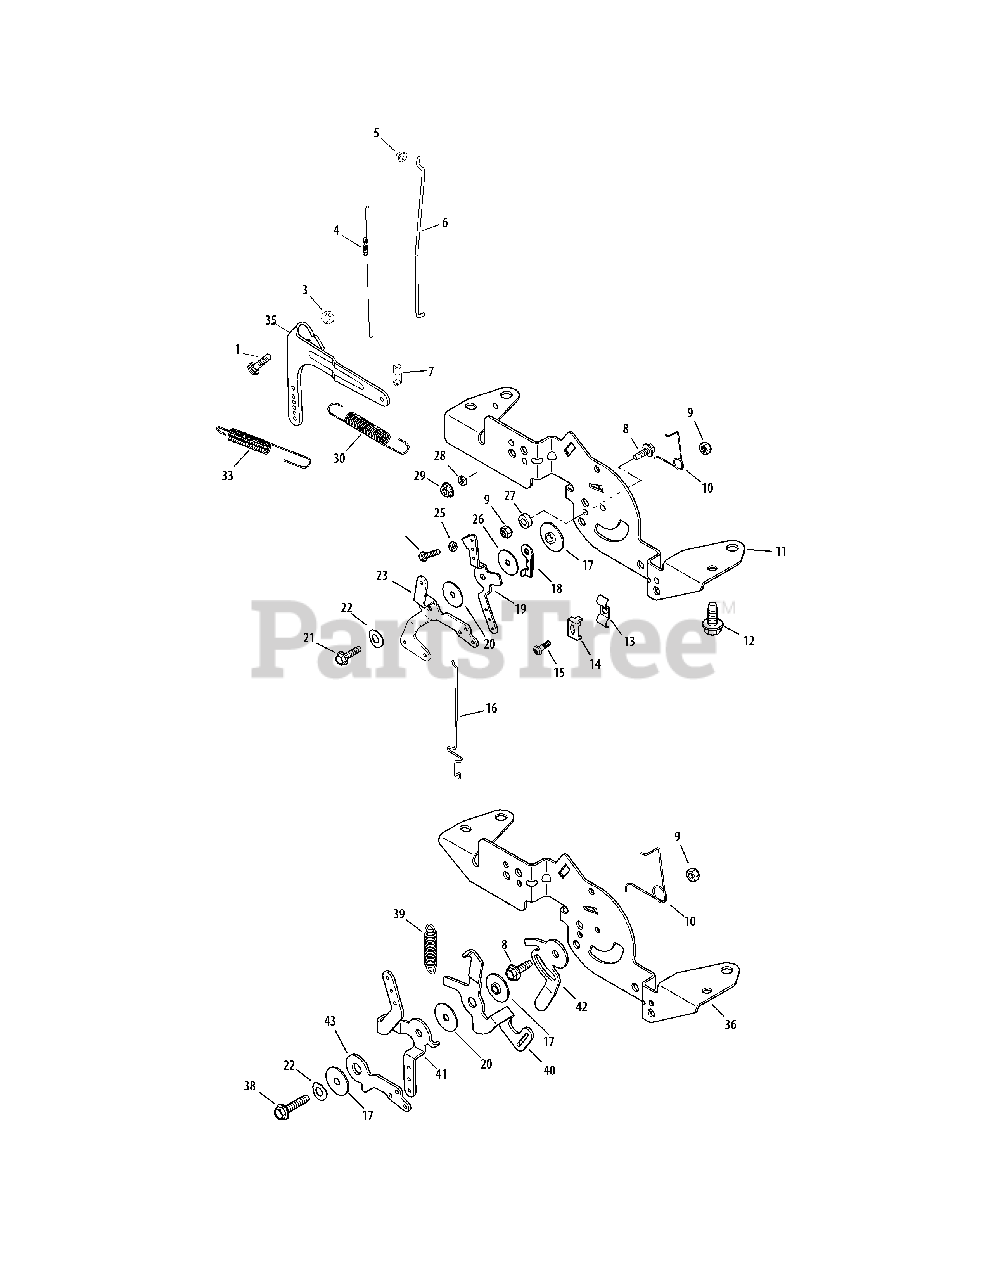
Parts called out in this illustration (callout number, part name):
1	Rd. Hd. Sq. Neck Bolt, M6 X 1.0 X 25
3	Flg. Nut, M6 X 1.0
4	Linkage Spring
5	Linkage Retaining Bushing
6	Throttle Linkage
7	Throttle Linkage Bushing
8	Flg. Thd. Frm. Screw, M5 X 0.8 X 16
9	Lock Nut, M5 X .8
10	Choke Return Spring
11	Not used in this application
12	Flg. Thd. Frm. Screw, M6 X 1.0 X 16
13	Not used in this application
14	Cable Clamp
15	Lbd. Thd. Frm. Screw, M5 X 0.8 X 16
16	Choke Linkage
17	Control Assembly Spacer
18	Not used in this application
19	Not used in this application
20	Flat Washer. 5.5mm
21	Not used in this application
22	Spring Washer, 1/4
23	Not used in this application
25	Not used in this application
26	Not used in this application
27	Not used in this application
28	Not used in this application
29	Not used in this application
30	Governor Spring
33	Governor Spring
35	Governor Lever
36	Control Bracket
38	Thd. Frm. Screw, M5 X 0.8 X 25mm
39	Speed Control Spring
40	Governor Spring Lever
41	Speed Control Lever
42	Speed Setting Lever
